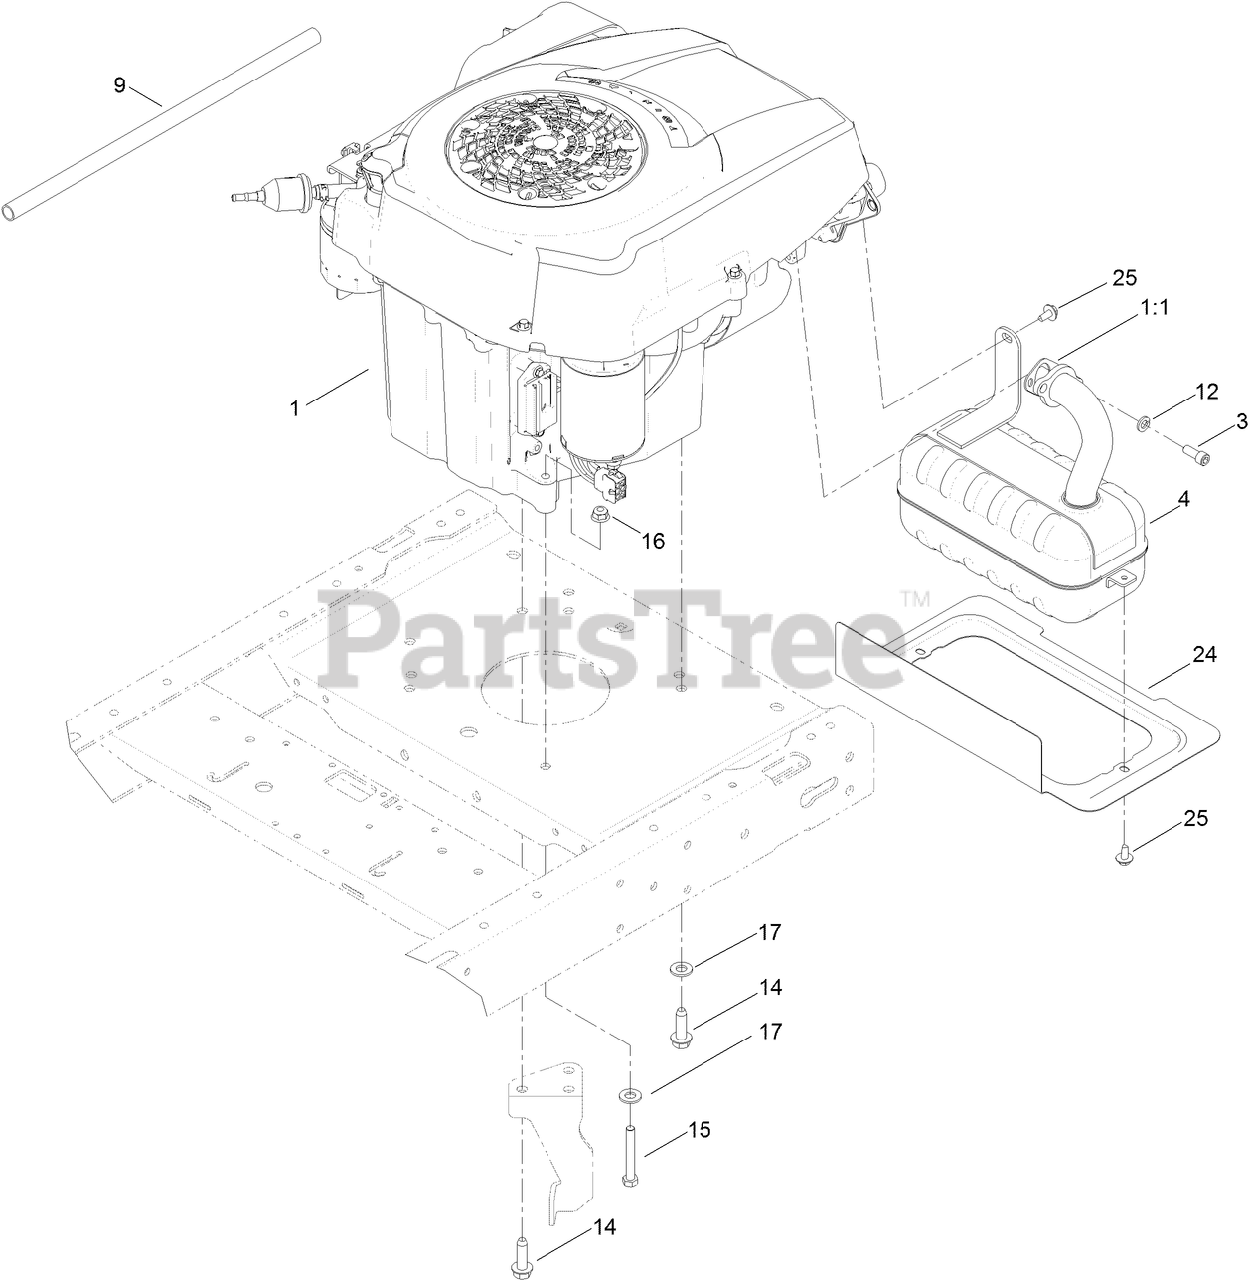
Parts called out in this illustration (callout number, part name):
1:1	GASKET-EXHAUST
3	SCREW-HSH
4	MUFFLER-KOHLER
9	TUBE-DRAIN, OIL
12	WASHER-LOCK
14	SCREW-THD
15	SCREW-HH
16	NUT-HF, NI
17	WASHER-FLAT
24	SHIELD-HEAT
25	SCREW-HHFTF
